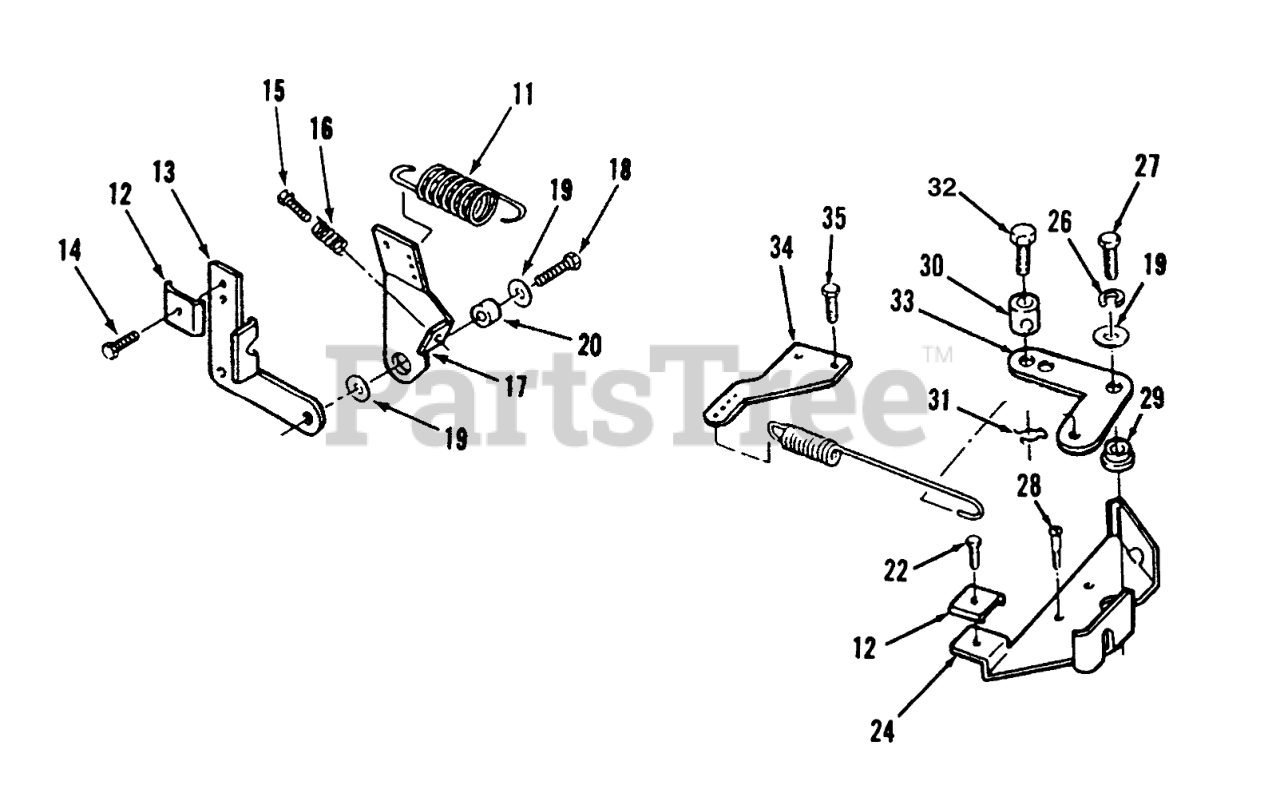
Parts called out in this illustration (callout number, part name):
11	SPRING
13	BRACKET
14	SCREW-TAPPING
15	SCREW-TAP
16	SPRING
17	GOVERNOR CONTROL ARM
18	SCREW-HWH
19	WASHER-FLAT
20	BUSHING
22	TAPPING HEX HD CS
24	BRKT-GOVERNOR CONTRL
26	WASHER-LOCK, SPRING
27	SCREW - CAP HEX HEAD
29	BUSHING-GOV CONTROL
31	PIN-COTTER
32	SCREW
33	LINK-GOV CONTROL
34	ADAPTER-GOV ARM
35	SCREW-TAPPING PAN HD
